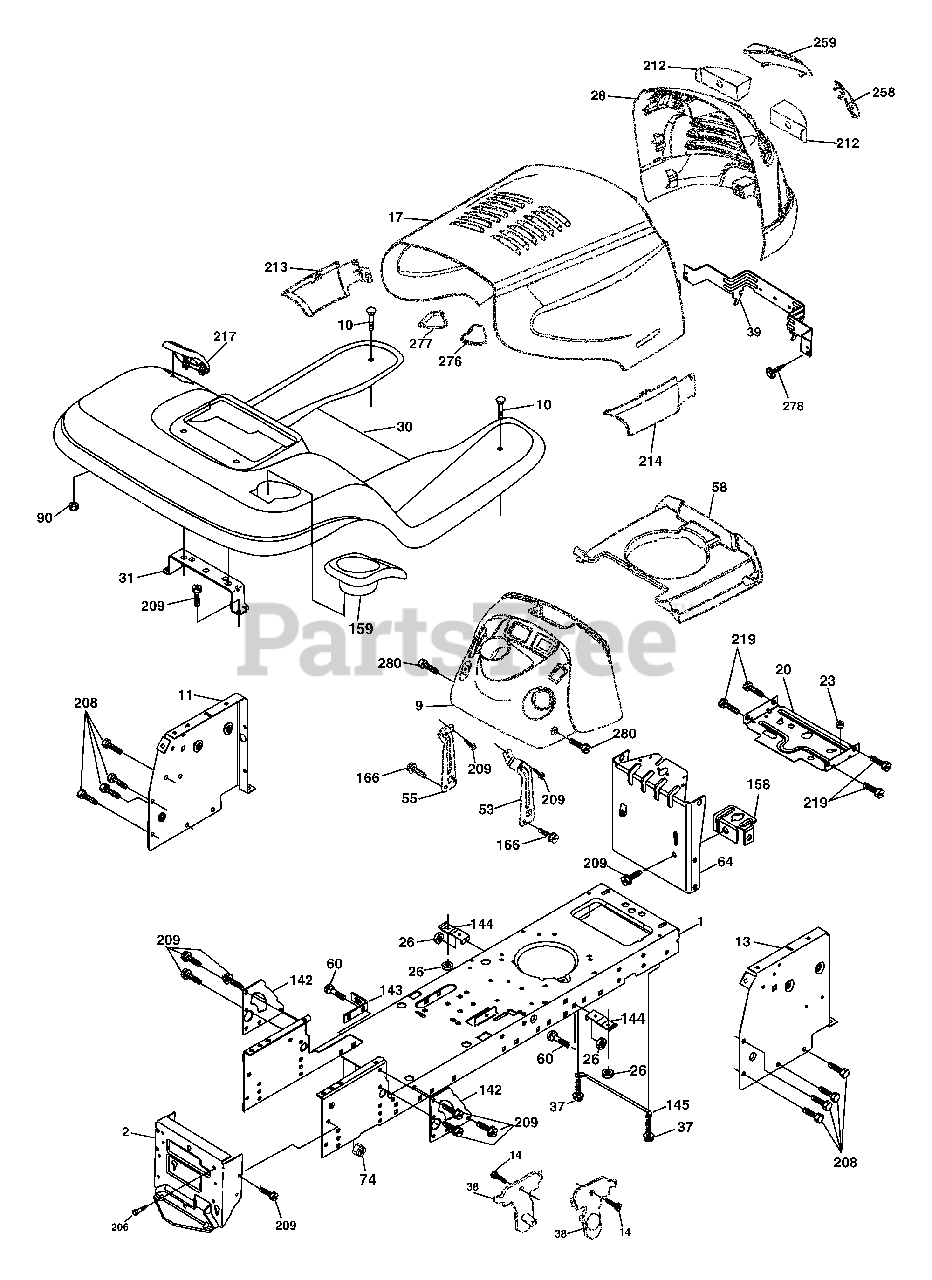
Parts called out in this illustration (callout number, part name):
1	Chassis Stamping
9	Dash
10	Bolt Rdhd Sqnk 3/8-16 unc x 1
11	Panel Dash Lh
13	Panel Dash Rh
14	Screw Thdrol 3/8-16 x 1/2
17	Hood
20	Plate Mtg Battery/Fuel Tank
26	Nut Lock w/Insert 3/8-16 unc
28	Grille Lens Asm
30	Fender
37	Screw Thdrol 5/16-18 x 1/2
38	Bracket Asm Pivot Mower Rear
39	Bracket Pivot
53	Bracket Dash RH
55	Bracket Dash LH
58	Duct Air
60	Bolt RDHD SQNK 3/8-16 x 3/4
64	Dash Lower
74	Nut Crownlock 3/8-16
142	Plate Reinforcement
143	Bracket Swaybar Chassis
144	Bracket Ft Rest
145	Rod Pivot Chassis Hood
158	Bracket Parking Brake
159	Cupholder
166	Screw Hw Hd Hi-Lo #13-16 x 3/4
208	Screw Thdrol 3/8-16 x 1/2 Ty-TT
209	Screw 3/8-16 x 3/4
212	Lens Insert Reflect
213	Skirt Side LH
214	Skirt Side RH
217	Console Fuel Window
219	Screw 5/16-18 x 3/4
258	Lens RH
259	Lens LH
276	Bumper Hood RH
277	Bumper Hood LH
278	Screw Quadx WSHD #10-14 x 1
280	Screw 3/8-16 x 1
